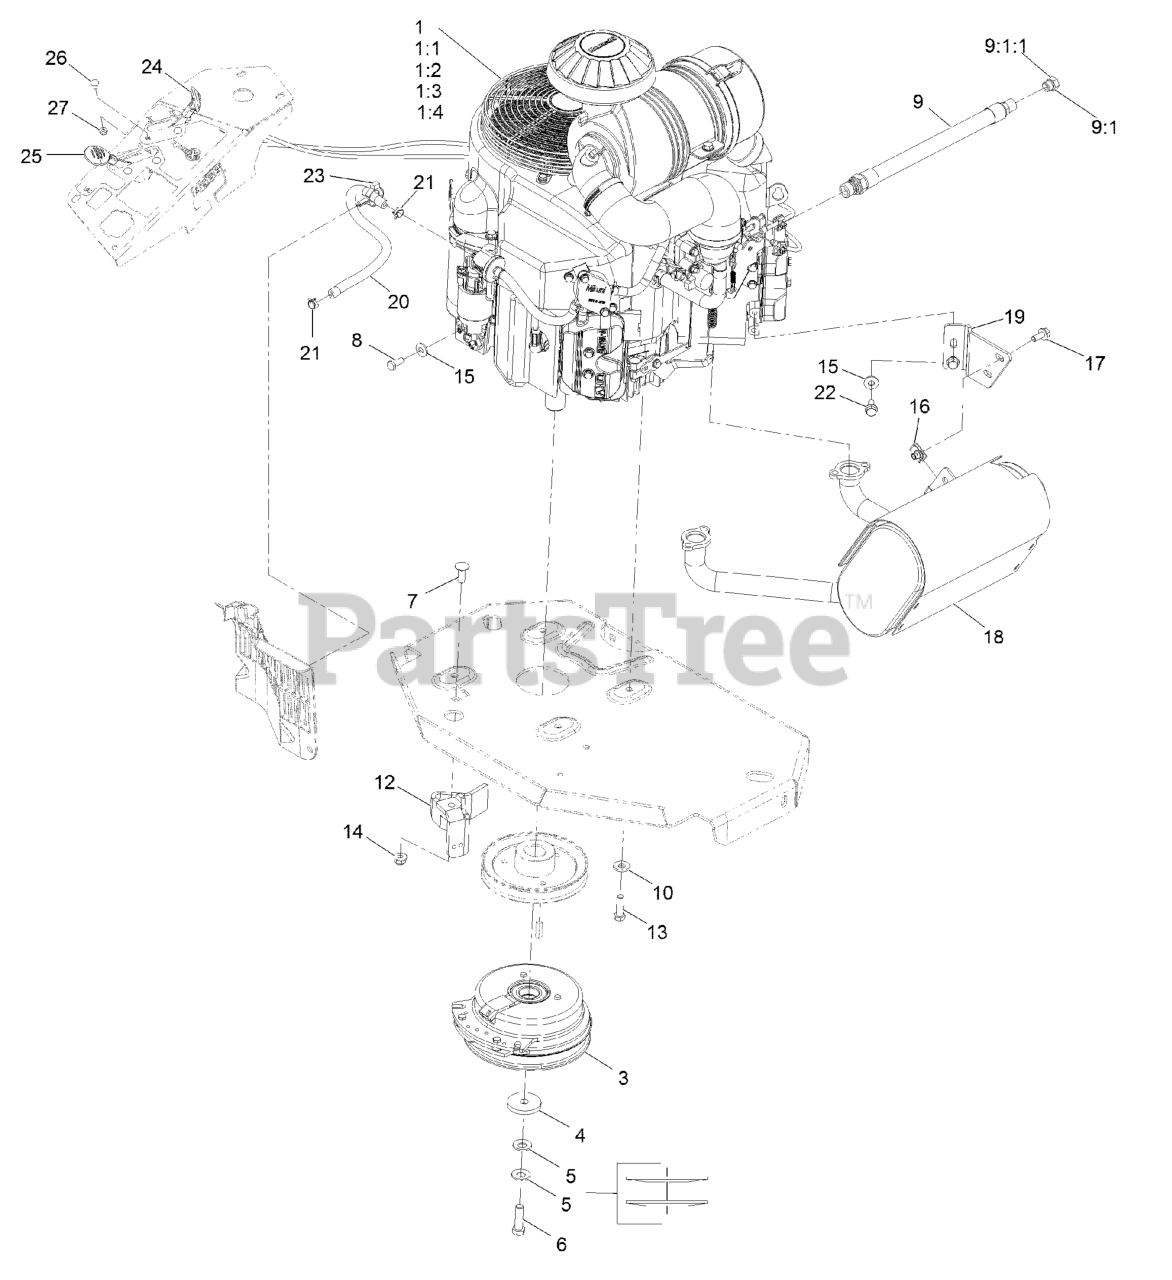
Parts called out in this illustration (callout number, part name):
1:1	Kawasaki 49065-2078 Engine Oil Filter
1:2	Kawasaki 49019-7001 Fuel Filter
1:3	Kawasaki 11013-7039 Safety Filter
1:4	Kawasaki 11013-7038 Air Filter
3	CLUTCH KIT
4	WASHER-CLUTCH
5	WASHER-SPRING
6	SCREW-HH 7/16-20 X 1 1/2 W/LOCTITE
7	SCREW-CARR
8	SCREW-HH
9	ENGINE OIL DRAIN HOSE ASM
9:1	PLUG-HH
9:1:1	O-RING
10	WASHER-BELLEVILLE
12	CLUTCH-ANCHOR
13	SCREW-HH
14	NUT-HF, NI
15	WASHER-SPRING
17	SCREW-HHF
18	MUFFLER
19	BRACKET-MUFFLER
20	HOSE-FUEL
21	CLAMP-HOSE
22	SCREW-HHF
23	CLAMP-HOSE
24	ASM, CHOKE CABLE
25	ASM,THROTTLE CABLE
26	BOLT-CARR
27	NUT-LOCK, NI
